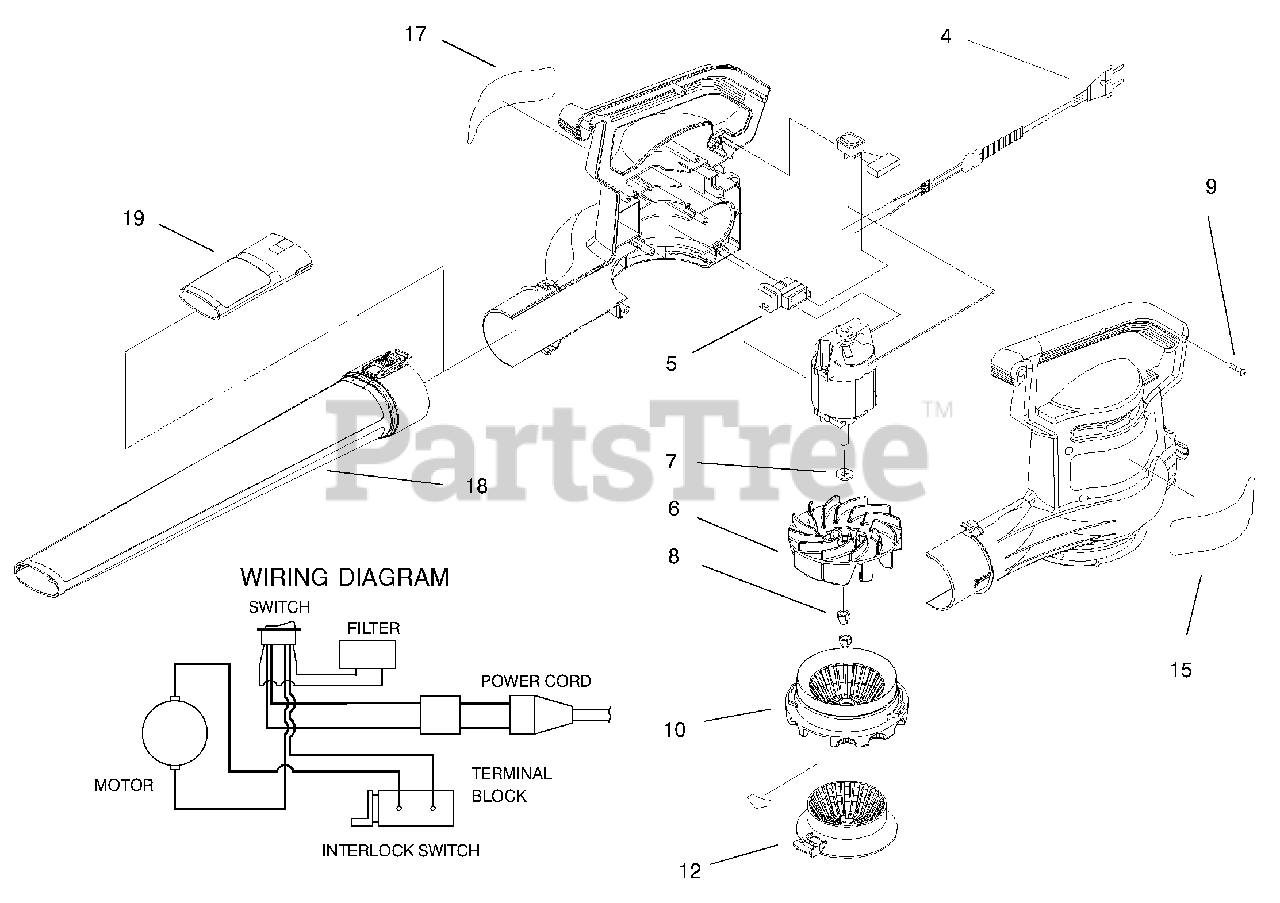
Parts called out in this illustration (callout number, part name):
4	Harness-Blower, 230 Volt (Australia)
5	Switch-Interlock
6	Impeller-Blower
8	Nut-Impeller
9	Screw-PPH
10	ASM-Inlet Cover & Decal
12	Choke-Air
15	Decal, Logo, Superblower
17	Label Stock-Serial, Australia
18	Tube-Blower
19	Insert-Tube
